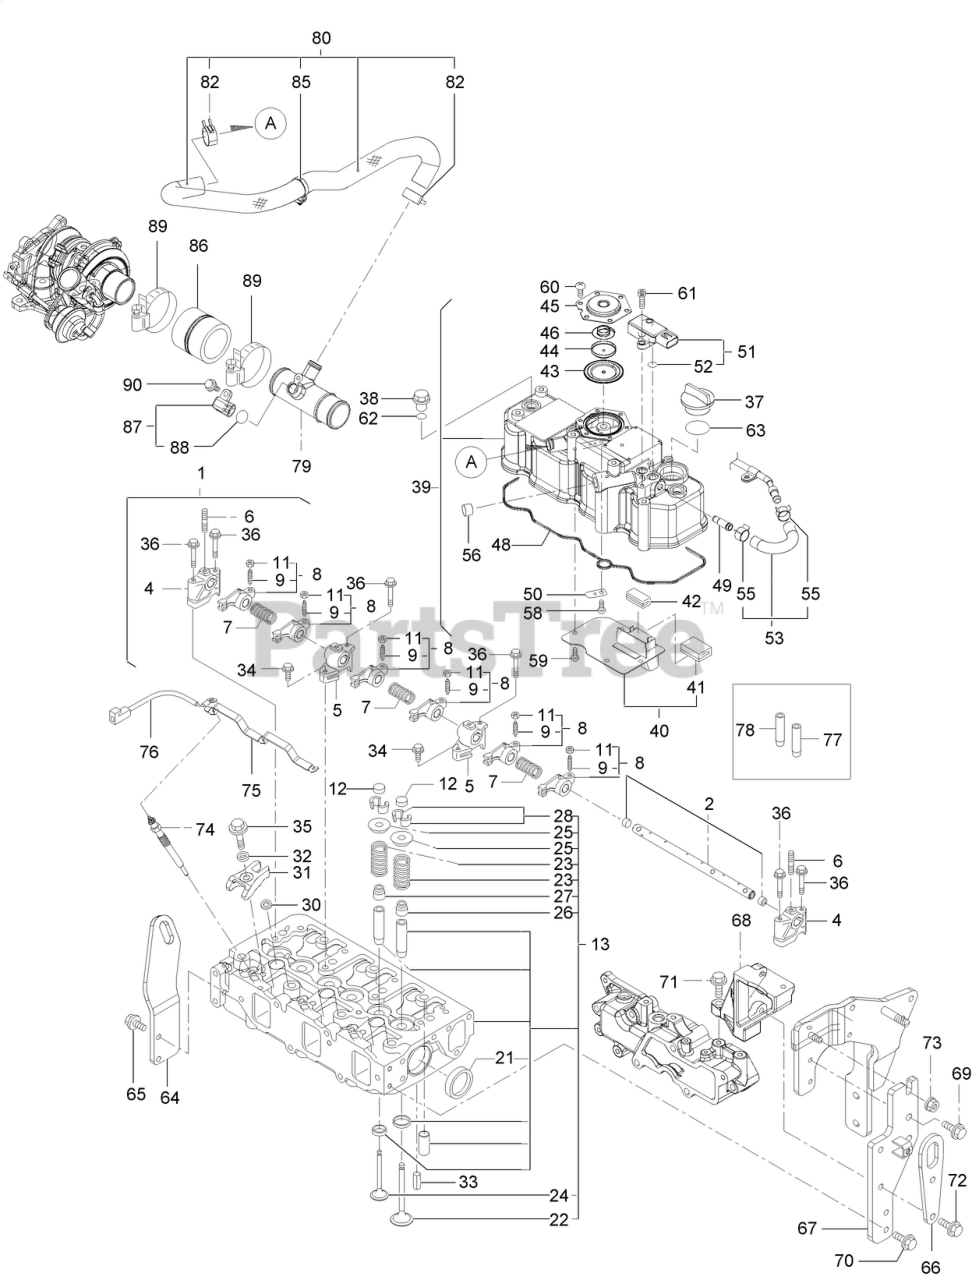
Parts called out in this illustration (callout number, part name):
1	SHAFT ASM
4	Support
5	Support
6	BOLT,STUD
8	Arm-Rocker
9	SCREW-ADJUST, VALVE
12	Cap-Valve
13	CYLINDER HEAD ASM
25	Retainer-Spring
26	SEAL-STEM, VALVE
27	SEAL-STEM, VALVE
28	PIN-COTTER
30	GASKET-INJECTOR
31	Retainer-Injector
32	WASHER-INJECTOR
33	PIN-SPRING
37	COVER-FILLER
39	CYLINDER HEAD ASM
43	DIAPHRAGM
45	PLATE-BREATHER
46	SPRING-DIAPHRAGM
48	GASKET-COVER, CYLINDER HEAD
51	SENSOR-PRESSURE
52	O RING-SENSOR, PRESSURE
53	HOSE ASM
55	Clip-Hose
64	LIFTER-ENGINE
66	LIFTER-ENGINE
67	STAY-D P F
68	STAY-BRACKET, FILTER
74	PLUG-GLOW
75	CONNECTOR-PLUG, GLOW
76	HARNESS-WIRE
78	GUIDE-VALVE
79	JOINT, BREATHER
80	HOSE ASSY, BREATHER
82	CLIP-HOSE
85	BAND-CLIP
86	HOSE-AIR
87	SENSOR-TEMP, AIR
89	CLAMP-HOSE
